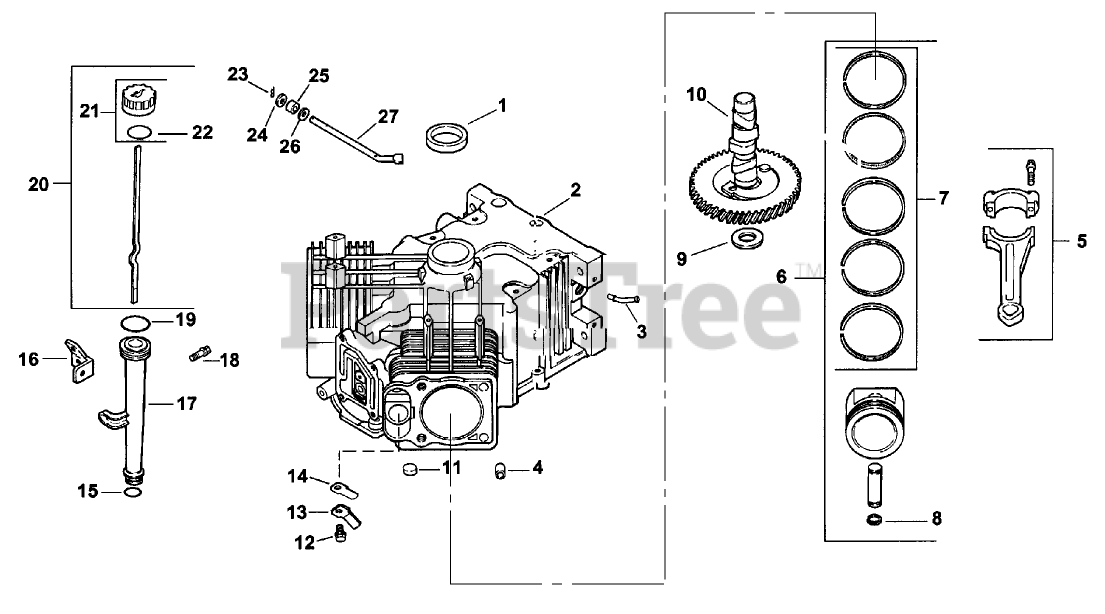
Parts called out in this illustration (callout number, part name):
1	SEAL-OIL
2	Use:Short Block or Miniblock
3	Fitting
4	Pin, dowel locating
5	Rod-Connecting (Standard)
6	Piston w/Ring Set Std. (Includes 7-8)
7	Ring Set (.25)
8	RETAINER-PIN, PISTON
9	SHIM-CAMSHAFT (RED .032)
10	Camshaft Kit
11	PLUG-CUP
12	Screw
13	RETAINER-REED, BREATHER
14	Reed-Breather
15	O-RING
16	BRACKET-TUBE, OIL FILL
17	OIL FILL TUBE KIT
18	Screw, hex. flange
19	O-RING
20	Dipstick assembly (Includes 21,22)
21	Kit, oil fill cap (Includes 22)
22	O-Ring
23	Pin-Hitch
24	Washer-Flat
25	Seal-Cross Shaft, Governor
26	WASHER-FLAT (1/4)
27	Shaft-Governor Cross
